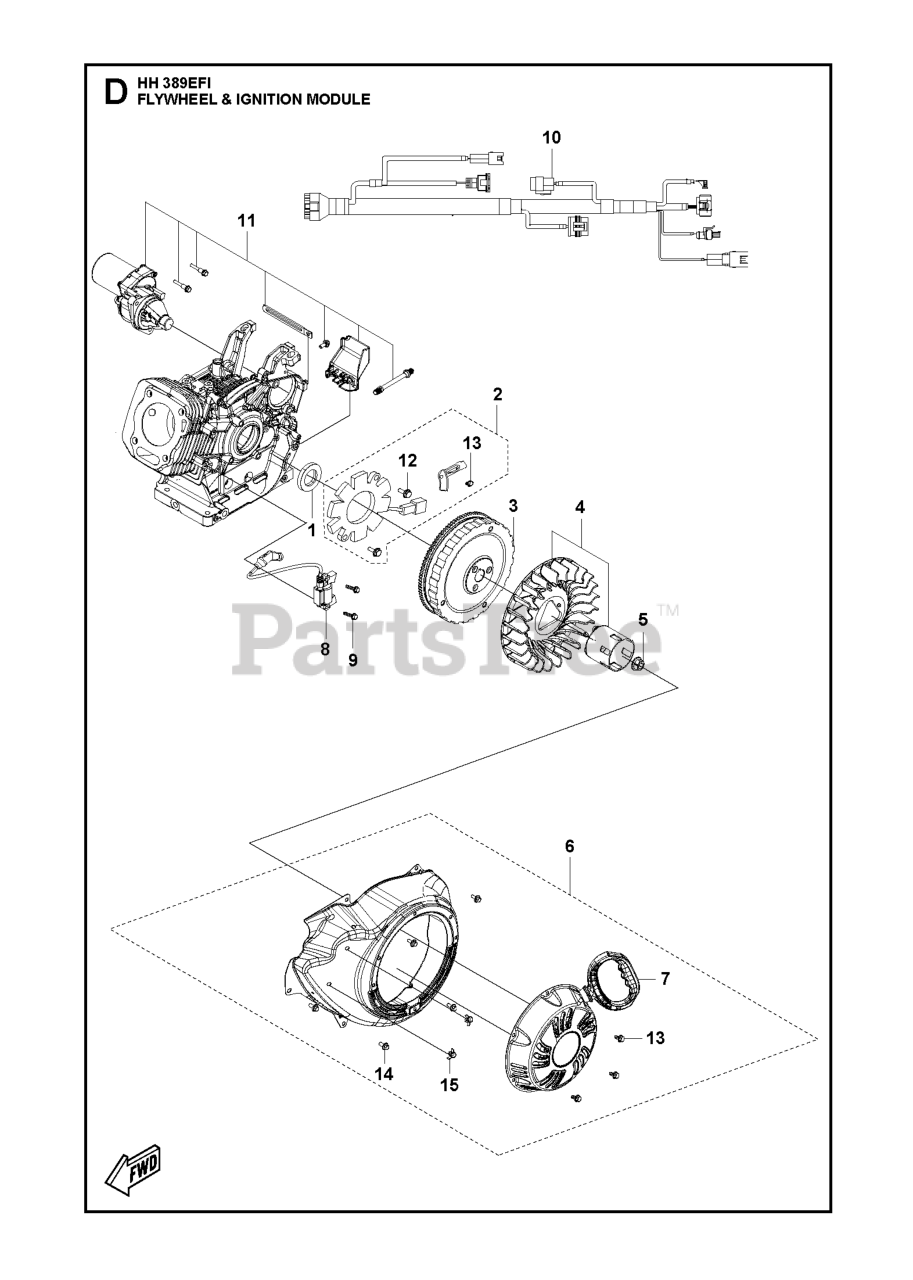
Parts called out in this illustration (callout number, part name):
1	SEAL OIL SEAL
2	COIL CHARGE COIL KIT
6	STARTER ASSY
7	STARTER HANDLE ASSY
8	IGNITION COIL
10	WIRE ECU WIRE
11	STARTER MOTOR
13	BOLT
14	BOLT
